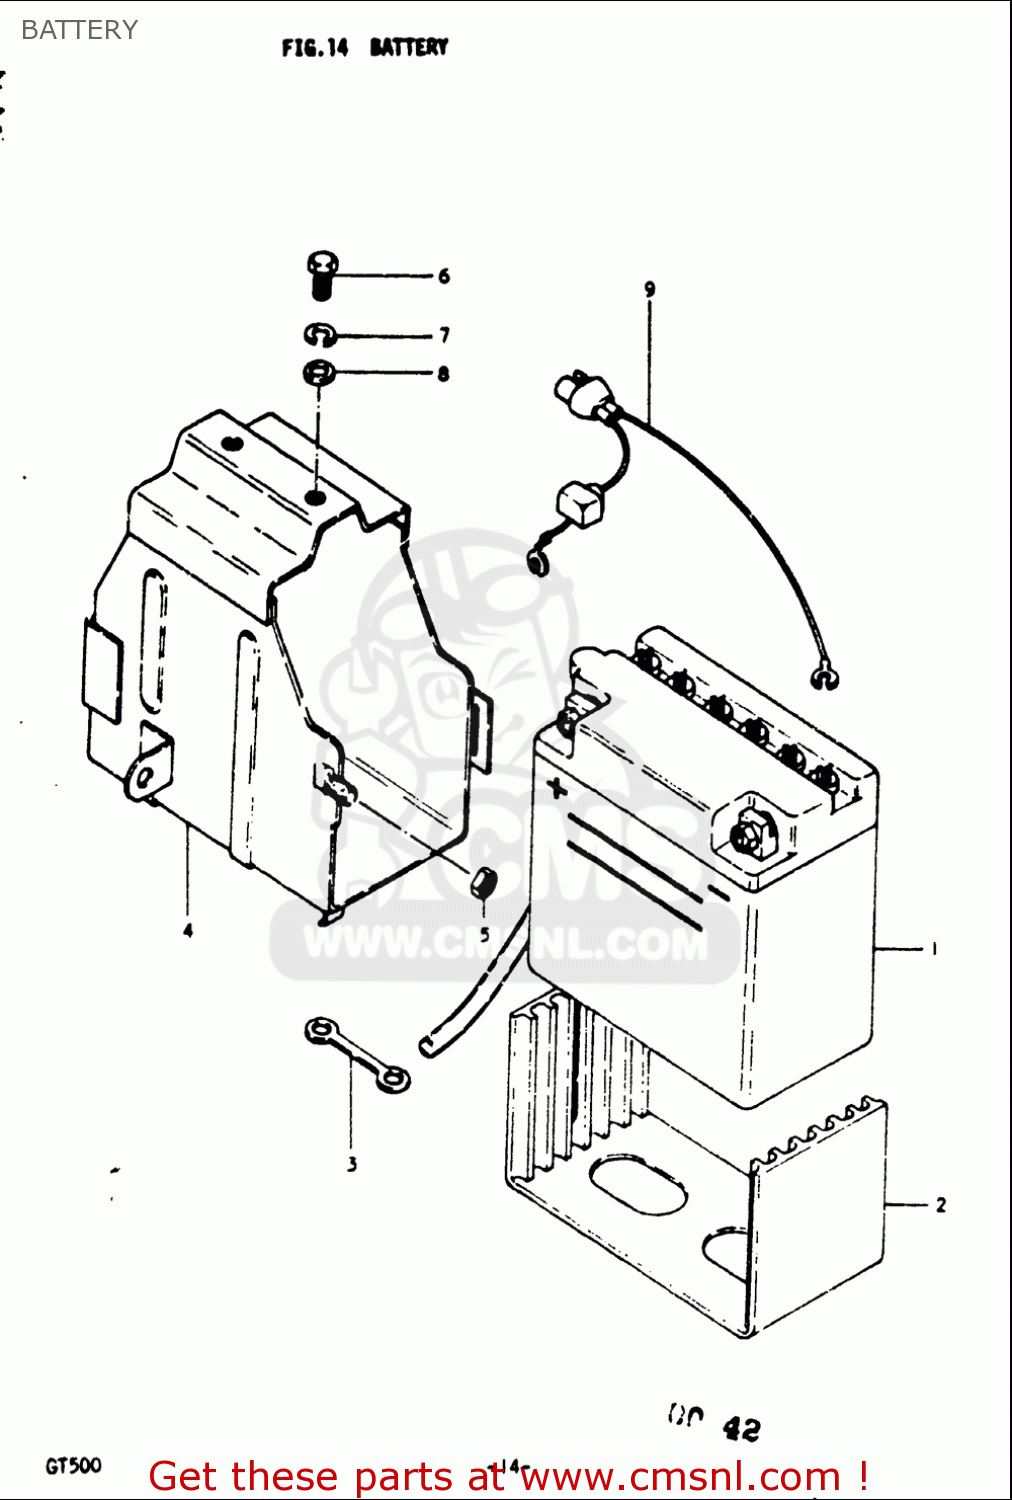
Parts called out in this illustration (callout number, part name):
1	BATTERY ASSY(YB7-A)
3	CLAMP
5	NUT
6	BOLT
7	WASHER,LOCK
8	WASHER
9	LEAD WIRE
